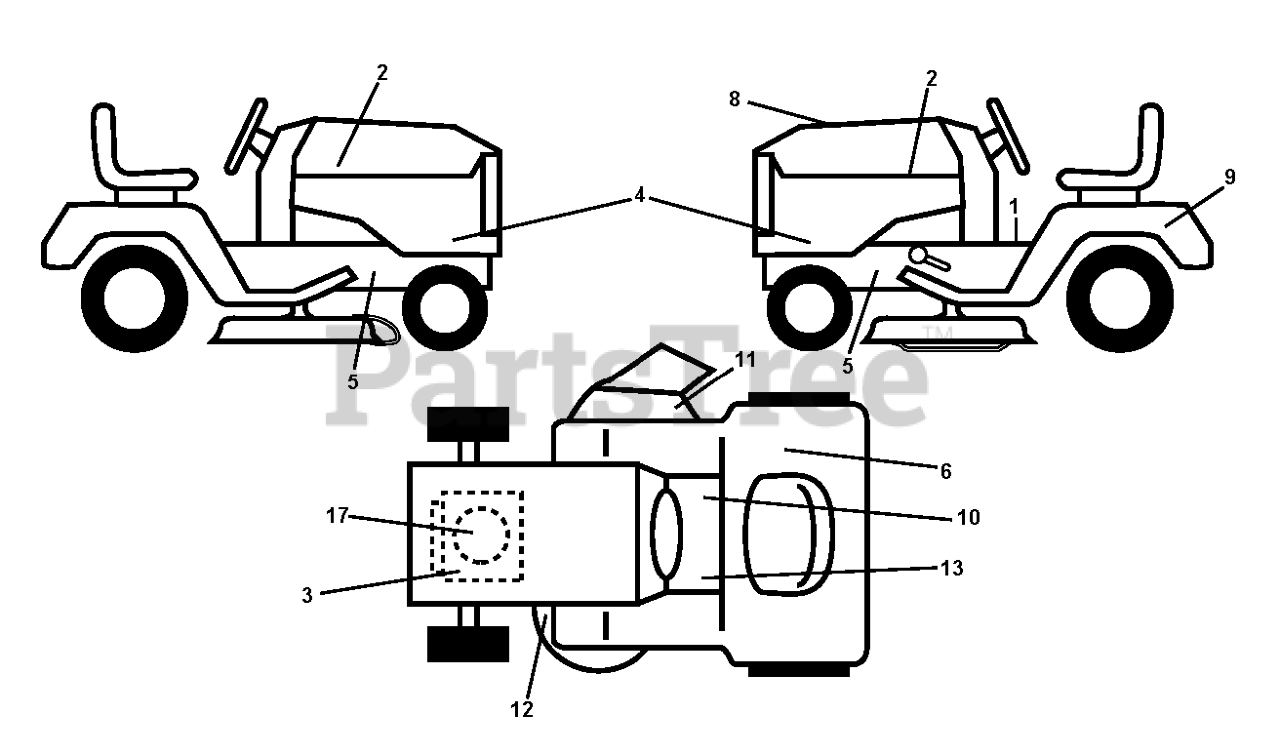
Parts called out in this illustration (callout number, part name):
1	LABEL
2	DECAL.HOOD.LOGO.ORANGE.HUSQVAR
3	DECAL
4	Decal, Hood Panel
6	Decal, Fender 100 DB/CE
8	Decal, Rpl
9	DECAL BTRY SYMBOLS
10	DECAL PARK BRAKE
11	DECAL, WARN. DEFLECT/CTFGR
12	Decal, Mower V-Belt Schematic
13	DECAL
